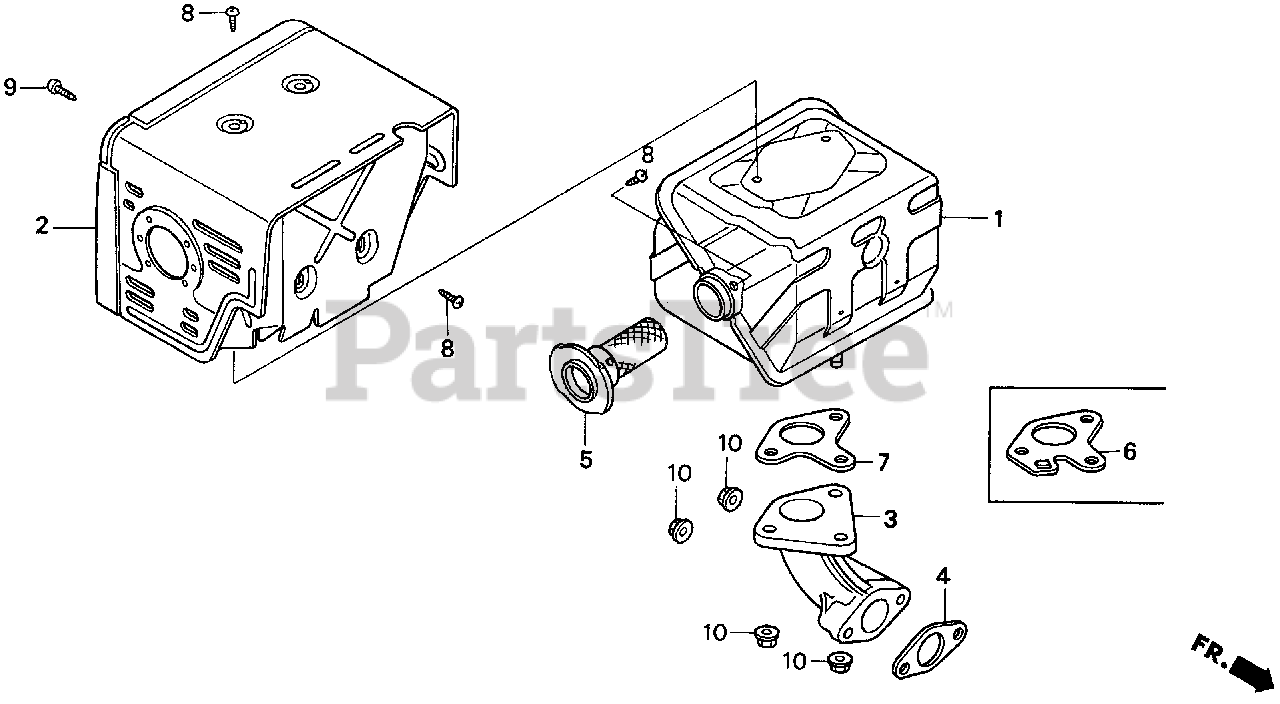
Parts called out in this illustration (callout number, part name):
1	MUFFLER (100DB) (SILENT)
1	MUFFLER (100DB)
2	PROTECTOR, MUFFLER
3	PIPE, EX.
4	GASKET, EX. PIPE
4	GASKET, EX. PIPE (WACKER)
5	ARRESTER, SPARK
6	GASKET, MUFFLER (ARRESTER)
7	GASKET, MUFFLER
8	SCREW, TAPPING (5X8)
9	SCREW, TAPPING (6X10)
10	NUT, FLANGE (8MM)
